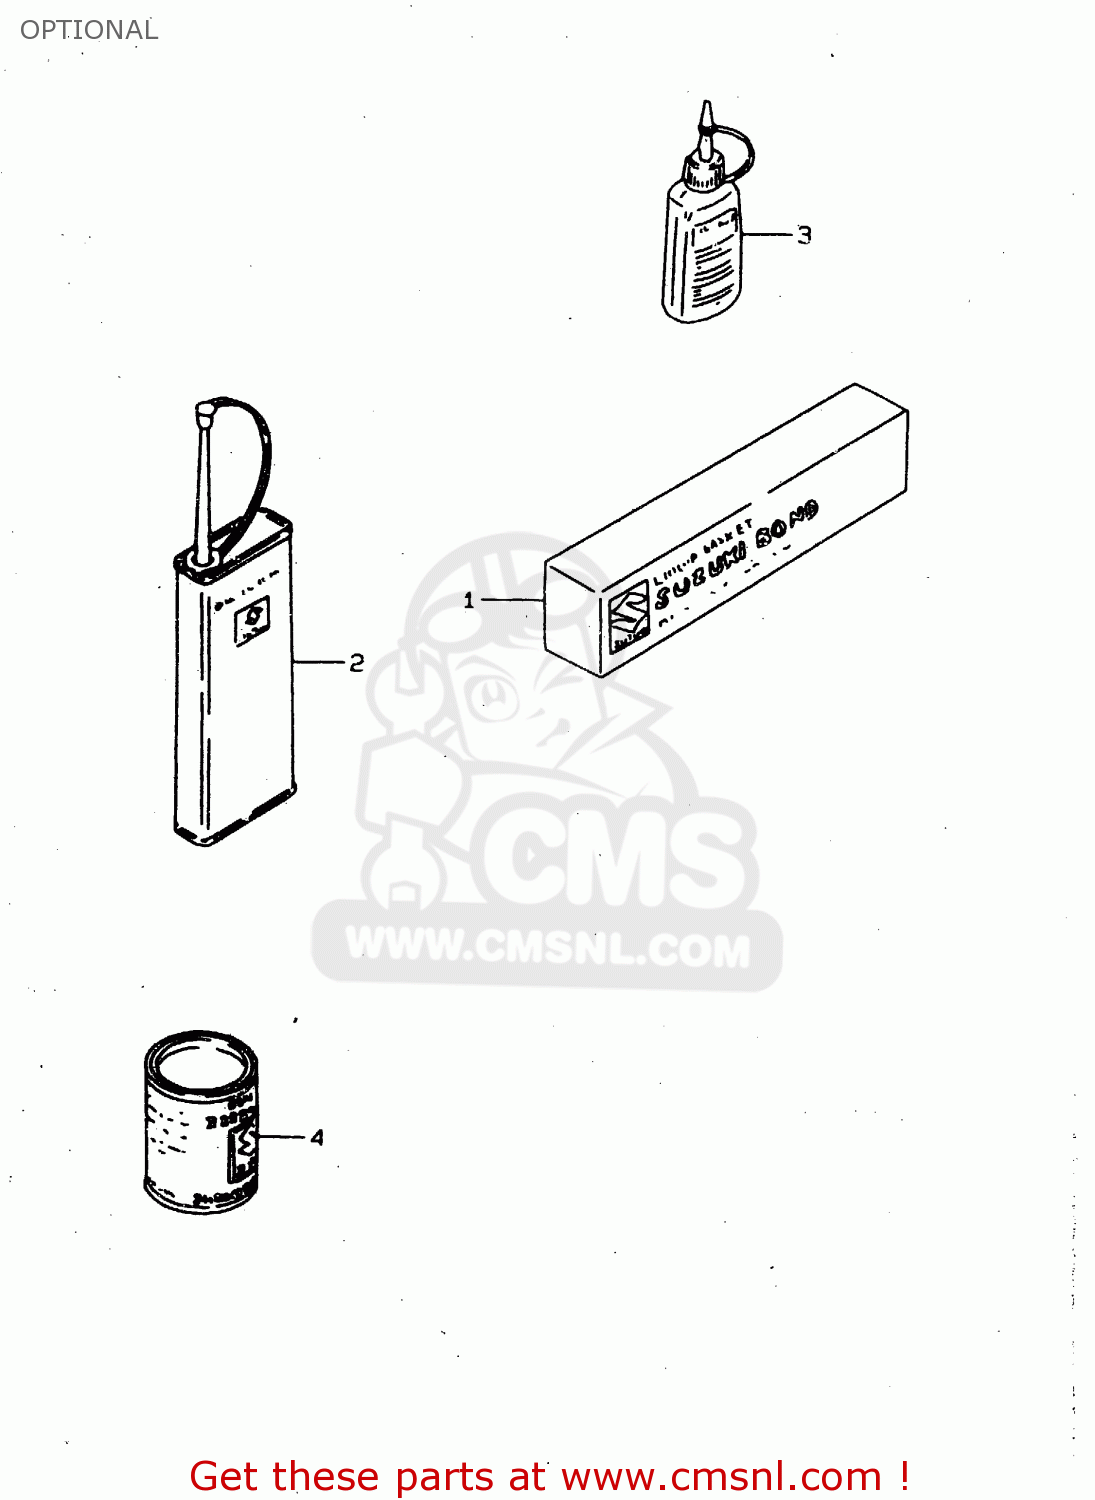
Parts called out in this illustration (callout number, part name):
1	BOND 1104
2	THREAD LOCK NO.1401 CLEAR 200G
3	** SUPERSEEDED
4	GREASE(C)EP2 LITHIUM 150G
